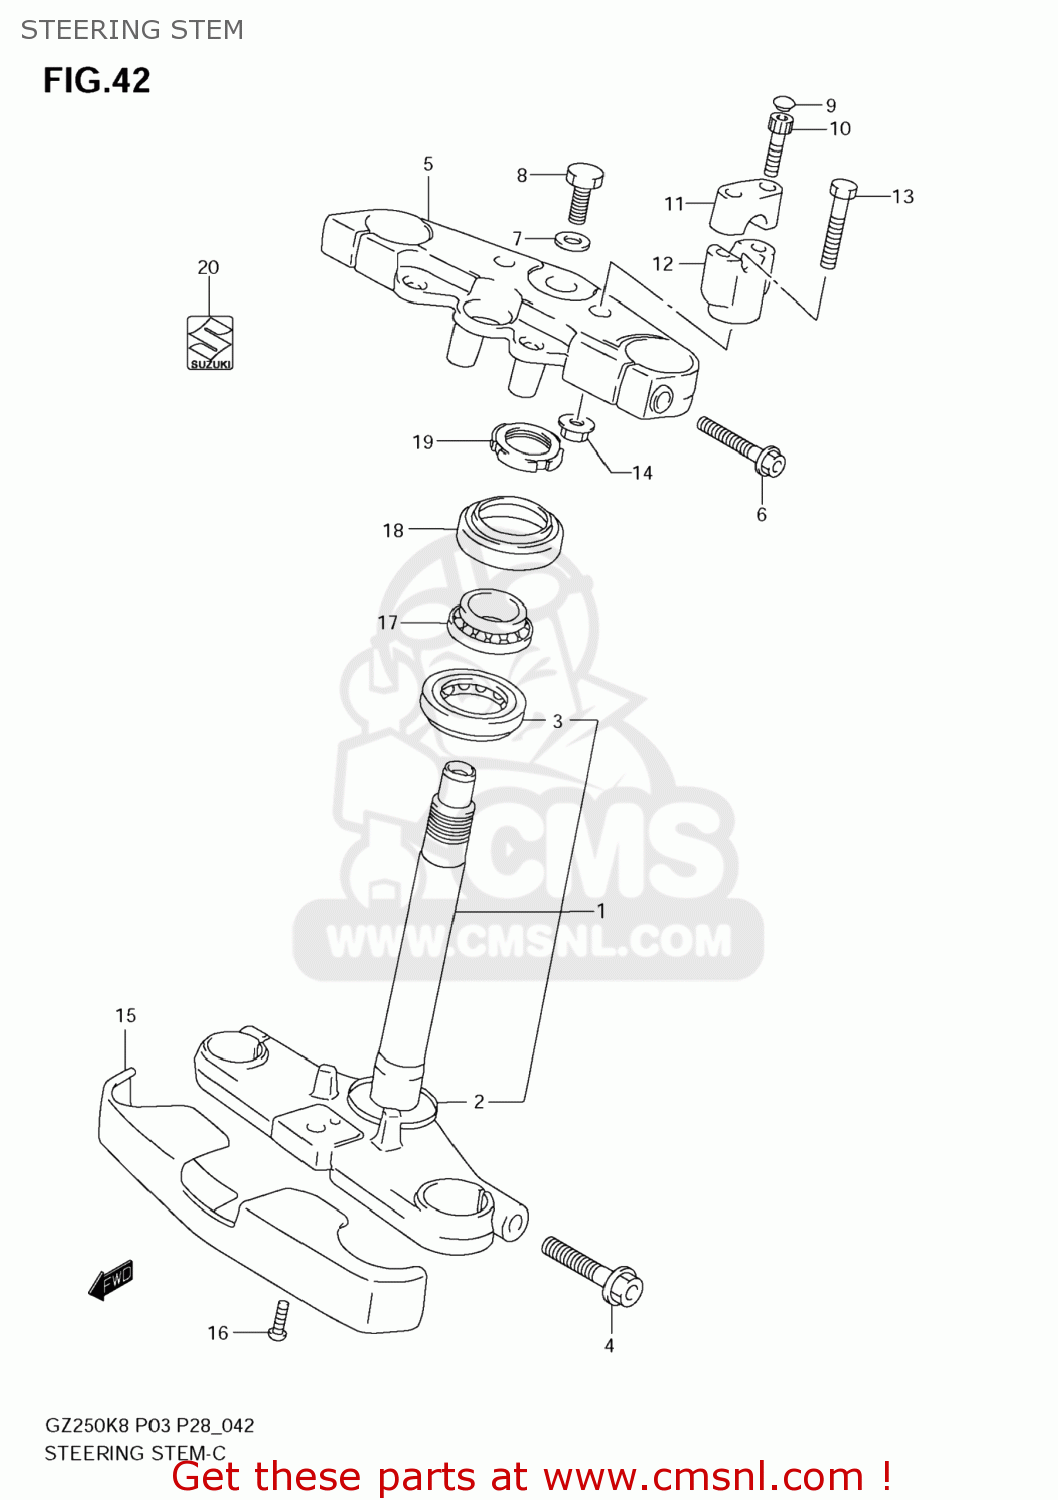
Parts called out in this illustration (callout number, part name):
1	STEM,STEERING
2	SEAL,STEERING LWR
3	BEARING(30X55X17)
4	BOLT
5	HEAD,STEERING STEM
6	BOLT
7	WASHER
8	BOLT
9	CAP(OD:11)
10	BOLT
11	HOLDER,HANDLE UPR
12	HOLDER, HANDLE LOWER
13	BOLT
14	NUT
15	COVER, FRONT FORK UNDER
16	SCREW(6X16)
17	BEARING(25X47X15)
18	DUST SEAL,STEERING UPR
19	NUT,STEERING STEM(25X44X10)
20	EMBLEM,S
